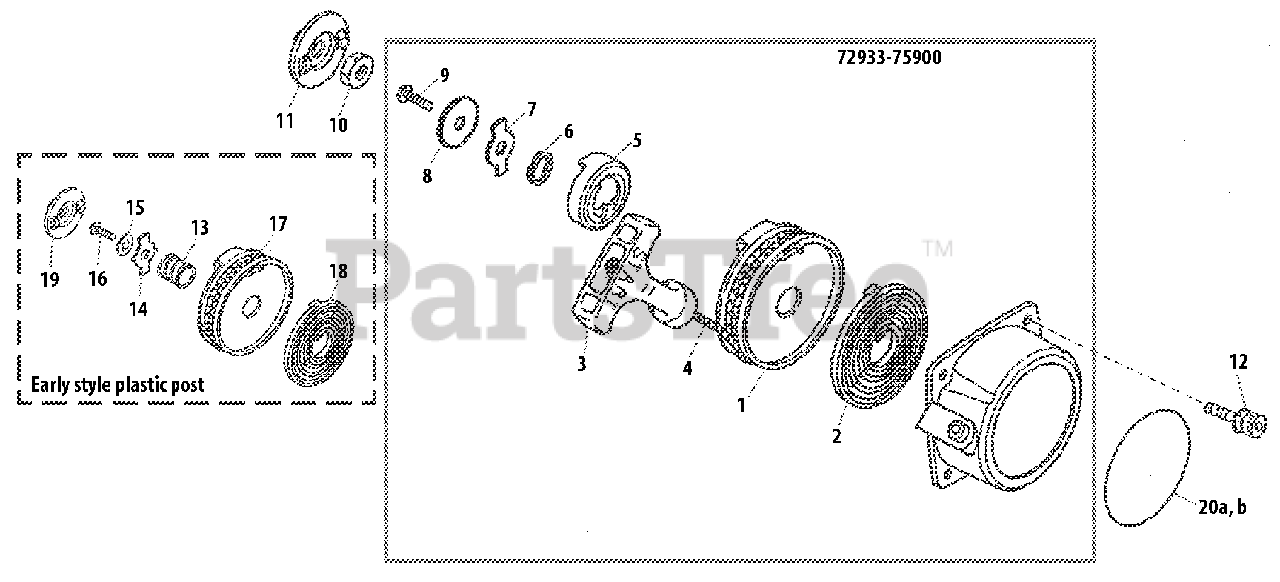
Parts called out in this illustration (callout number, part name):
1	REEL, ROPE
2	SPRING, REWIND
3	GRIP, STARTER
4	ROPE, STARTER
5	PAWL, STARTER
6	WASHER - SPRING
7	RETAINER
8	WASHER - 5
9	SCREW - 5
10	NUT - 8
11	PAWL
12	SCREW - 4X12
13	SPRING
14	RETAINER
15	WASHER
17	REEL, ROPE
18	SPRING
19	REEL, ROPE
20	LABEL - IDENTIFICATION
20	LABEL - MODEL T230XB
72933-75900	STARTER ASSY
